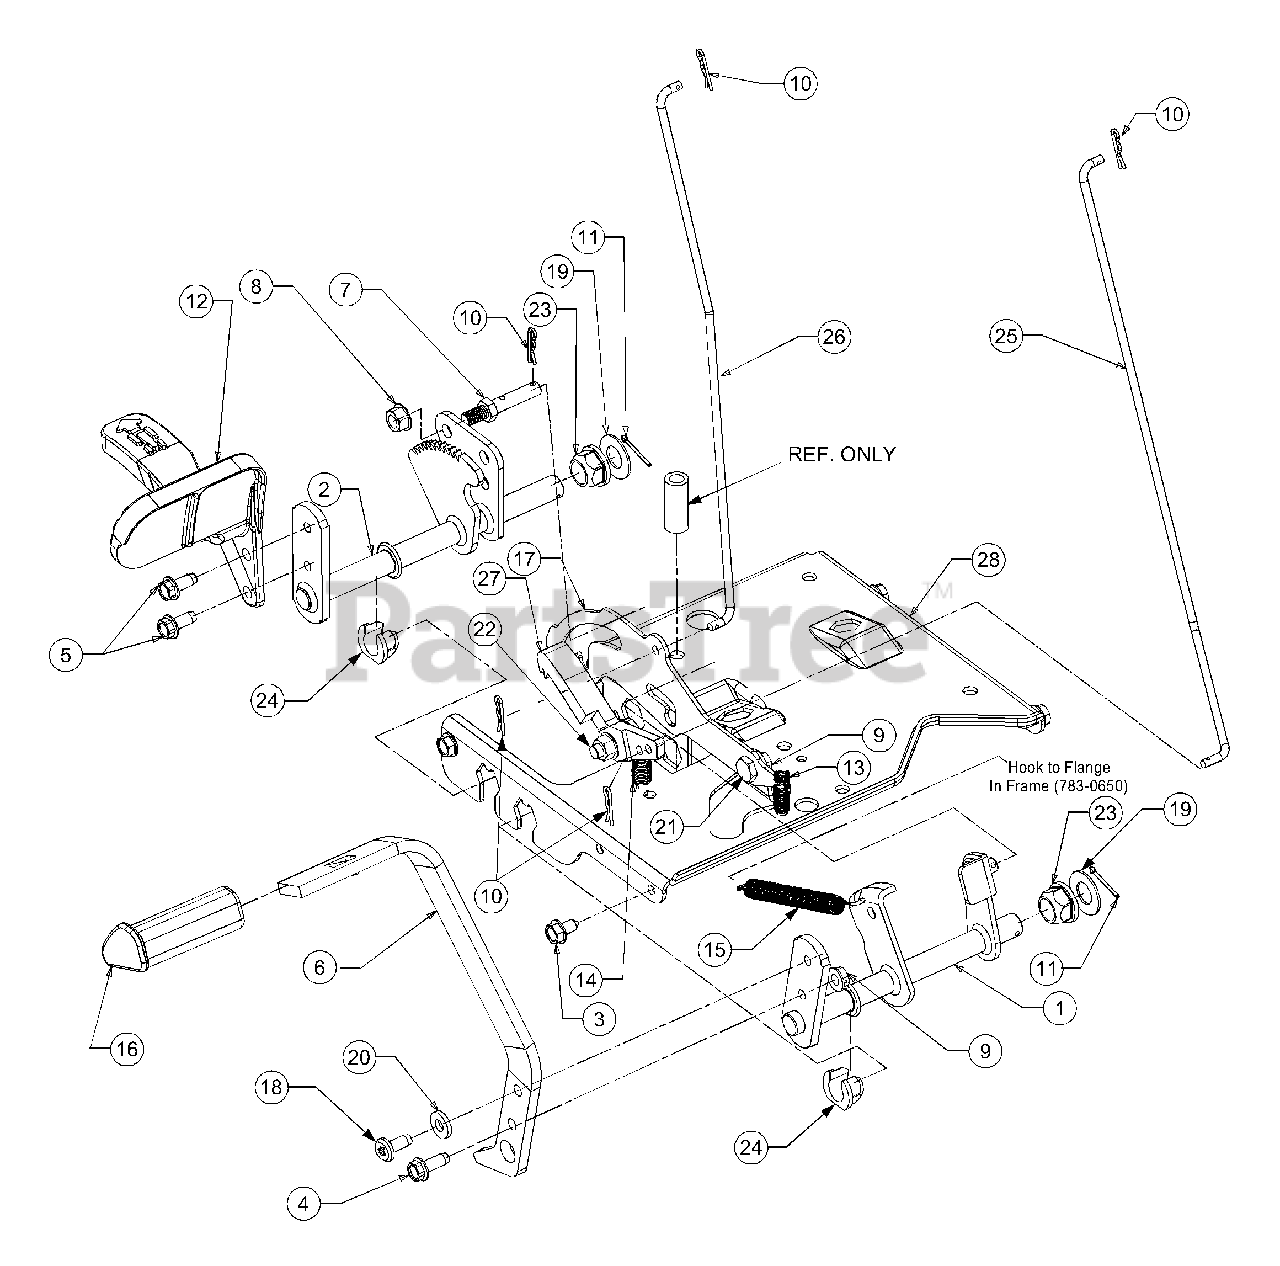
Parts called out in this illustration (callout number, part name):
4	Screw, Self-tapping, 5/16-18, 0.875
5	Screw, 5/16-18, 0.750
8	Nut, Nylon Lock, 3/8-16
9	Nut, Nylon Lock, 5/16-18, Gr5
10	Pin, Cotter, .072 Dia. x 1.13 Lg
11	Pin, Cotter, 3/32, 1.0
12	Pedal, Hydro Control
13	Spring, Compression, .405 x 1.17
14	Spring, Extension, .50 OD x 1.41 Lg
15	Spring, Extension, .50 Dia x 6.37 Lg
16	Pad, Brake, Control
17	Bracket, Lockout, Hydro
18	Screw, Torx Hd. Tapp. 5/16-18 x .75
19	Washer, Flat .64 ID x 1.24 x .06
20	Washer, Flat, .344 x .750 x .120
21	Shoulder, Screw .437 x 1.62 Lg
22	Screw, Shoulder, .500 Dia x .434
23	Bearing, Hex Flange
24	Bearing, Hex Flange, .628 ID, Split
25	Rod, Control, Cruise
26	Rod, Control, Brake Lock
27	Latch, Cruise
